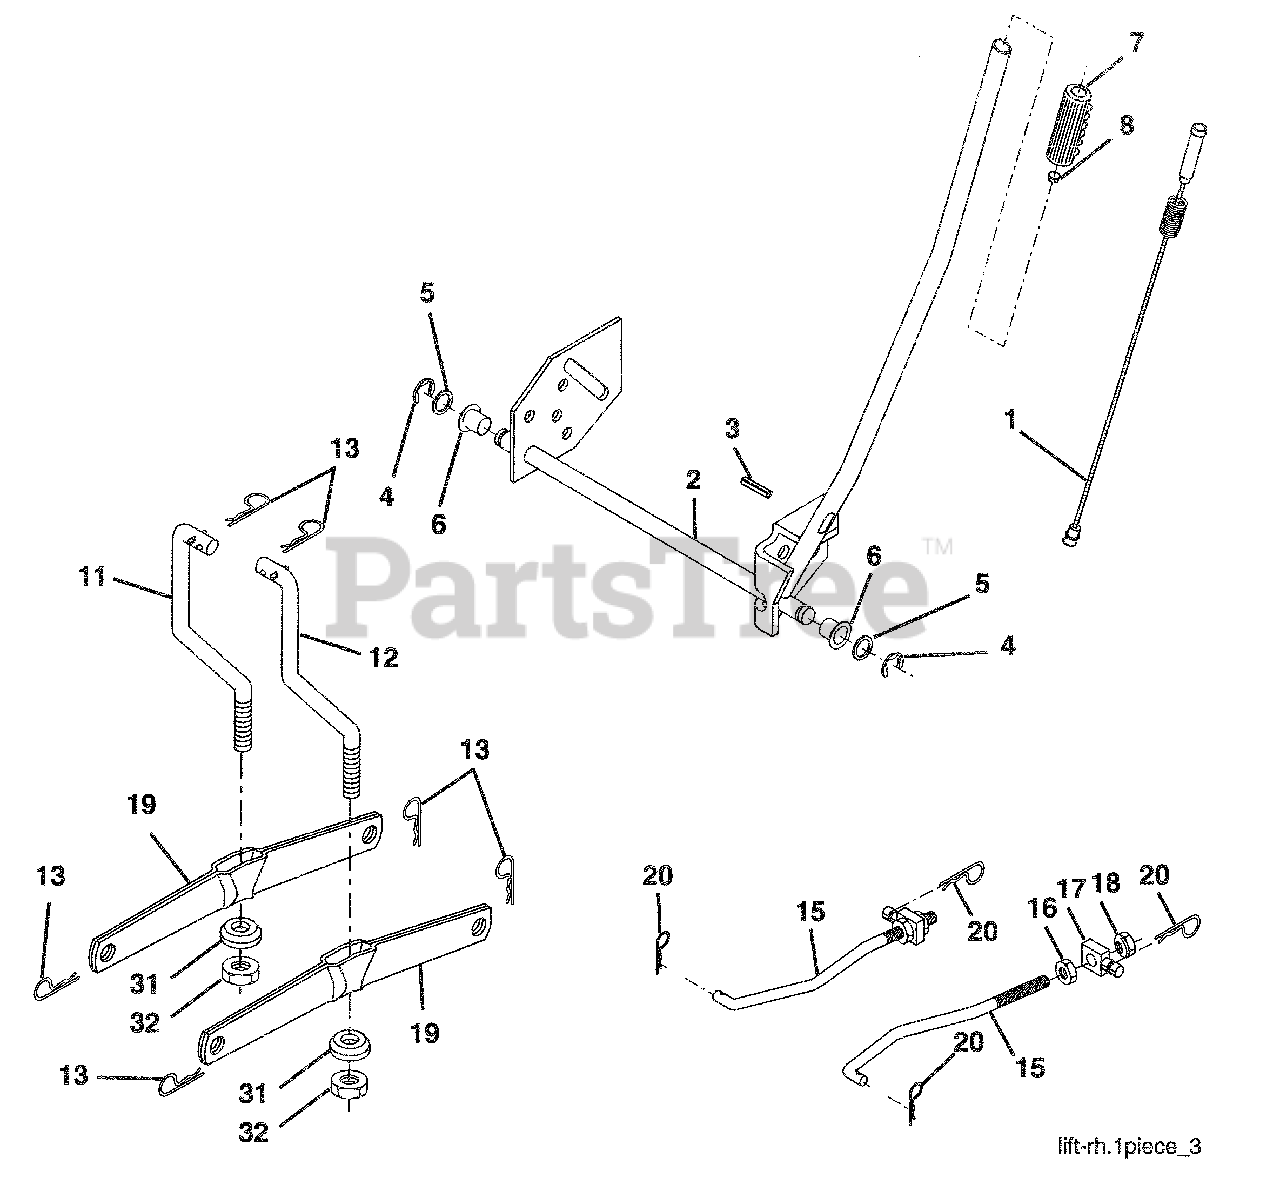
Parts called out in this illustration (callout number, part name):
1	Wire Asm Inner/Sprg w/plunger
2	Shaft Asm Lift RH
3	Pin Groove 1 500 Zinc
4	E Ring #5133-62
5	Washer 21/32 x 1 x 21 Ga.
6	Bearing Nylon Blk 629 Id
7	Grip Handle Bicycle Matte Blk
8	Button Plunger Black
11	Link Lift LH Fixed Length
12	Link Lift RH Fixed Length
13	Retainer Spring
15	Link Front
16	Nut Jam Hex 1/2-13 unc
17	Trunnion
18	Nut Lockw/Wsh 1/2-13 unc
19	Arm Suspension Rear
20	Retainer, Spring
31	Bearing Pvt Lift
32	Nut Crowniock 3/8-24
